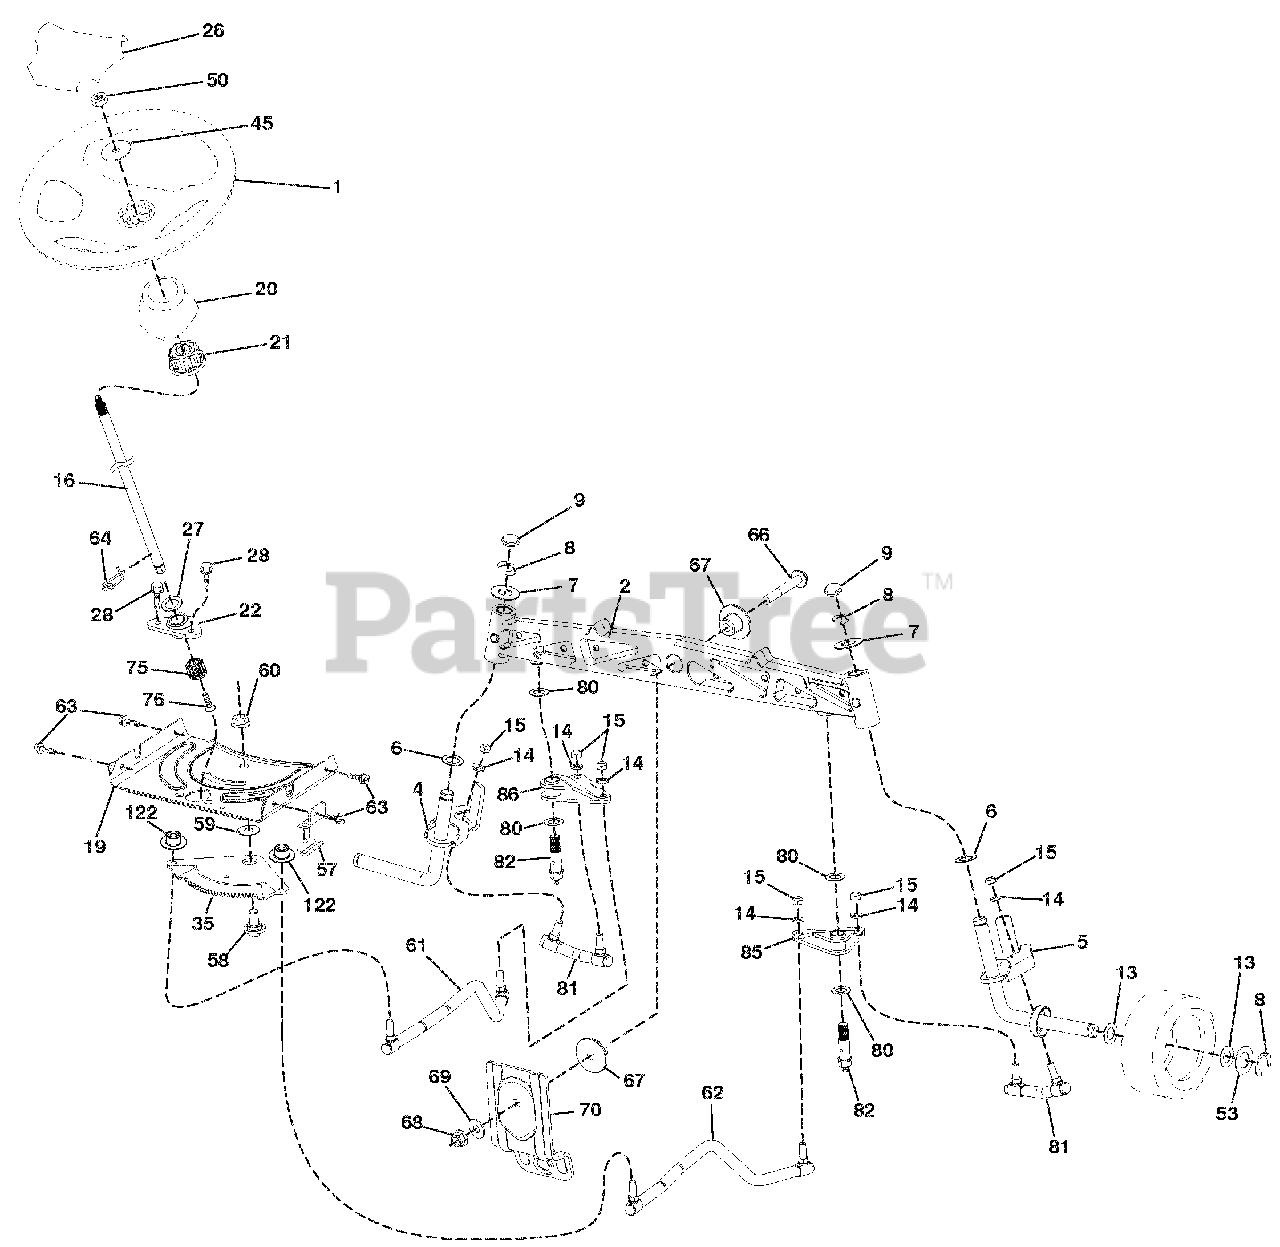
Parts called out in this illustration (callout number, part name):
1	WHEEL STEERING
4	SPINDLE LH
5	SPINDLE RH
6	WAHSER THRUST .75 X 1.230
7	WASHER.25/32 X 1-5/8 X 16GA.
8	RING.KLIP.#T5304-75
9	CAP.SPINDLE.FR.TOP.BLK.
13	WASHER.25/32 X 1 1/4 X 16 GA.
14	Washer, Lock 3/8
15	NUT.CROWNLOCK.3/8-24
16	SHAFT.STEER
19	PLATE.STEER.DDL.NLT/NGT
20	BOOT.STEERING
21	ADAPTER.STEER
22	BUSHING
26	CAP WHEEL STEERING HRS/SRS BLK
27	Washer 21/32 x 1 x 16 Ga.
28	SCREW.HEXWSH THDR3/8-16X3/4.BL
35	GEAR SECTOR
50	Nut, Hex, Flangelock 3/8-16
53	WASHER.HARDEN..793 X 1.637X060
57	BRACKET.UPSTOP.GT/LT.TEX
58	BOLT.SHOULDER.SECTOR.PIVOT.CFM
59	WASHER.THRUST.SECTOR.STEER.NLT
60	NUT.FLANGE LOCK.5/8-11
61	DRAG LINK LH
62	DRAG LINK RH
63	SCREW.5/16-18X3/4.SMGML.TAP/BL
64	RETAINER.CLIP.SPRING.STEERING
66	BOLT.HEX.FGHD.7/16-14 X 3.SERR
67	BUSHING.PM.FRONT AXLE
68	NUT.LOCK.FLANGE.7/16-14.GR5
69	WASHER.1.5 X .505 X .118
70	BRACKET
81	SUB ASM LINK
82	SUB ASM PIVOT BOLT
85	SUB ASM PIVOT RH
86	SUB ASM PIVOT LH
122	CAP GEAR SECTOR
